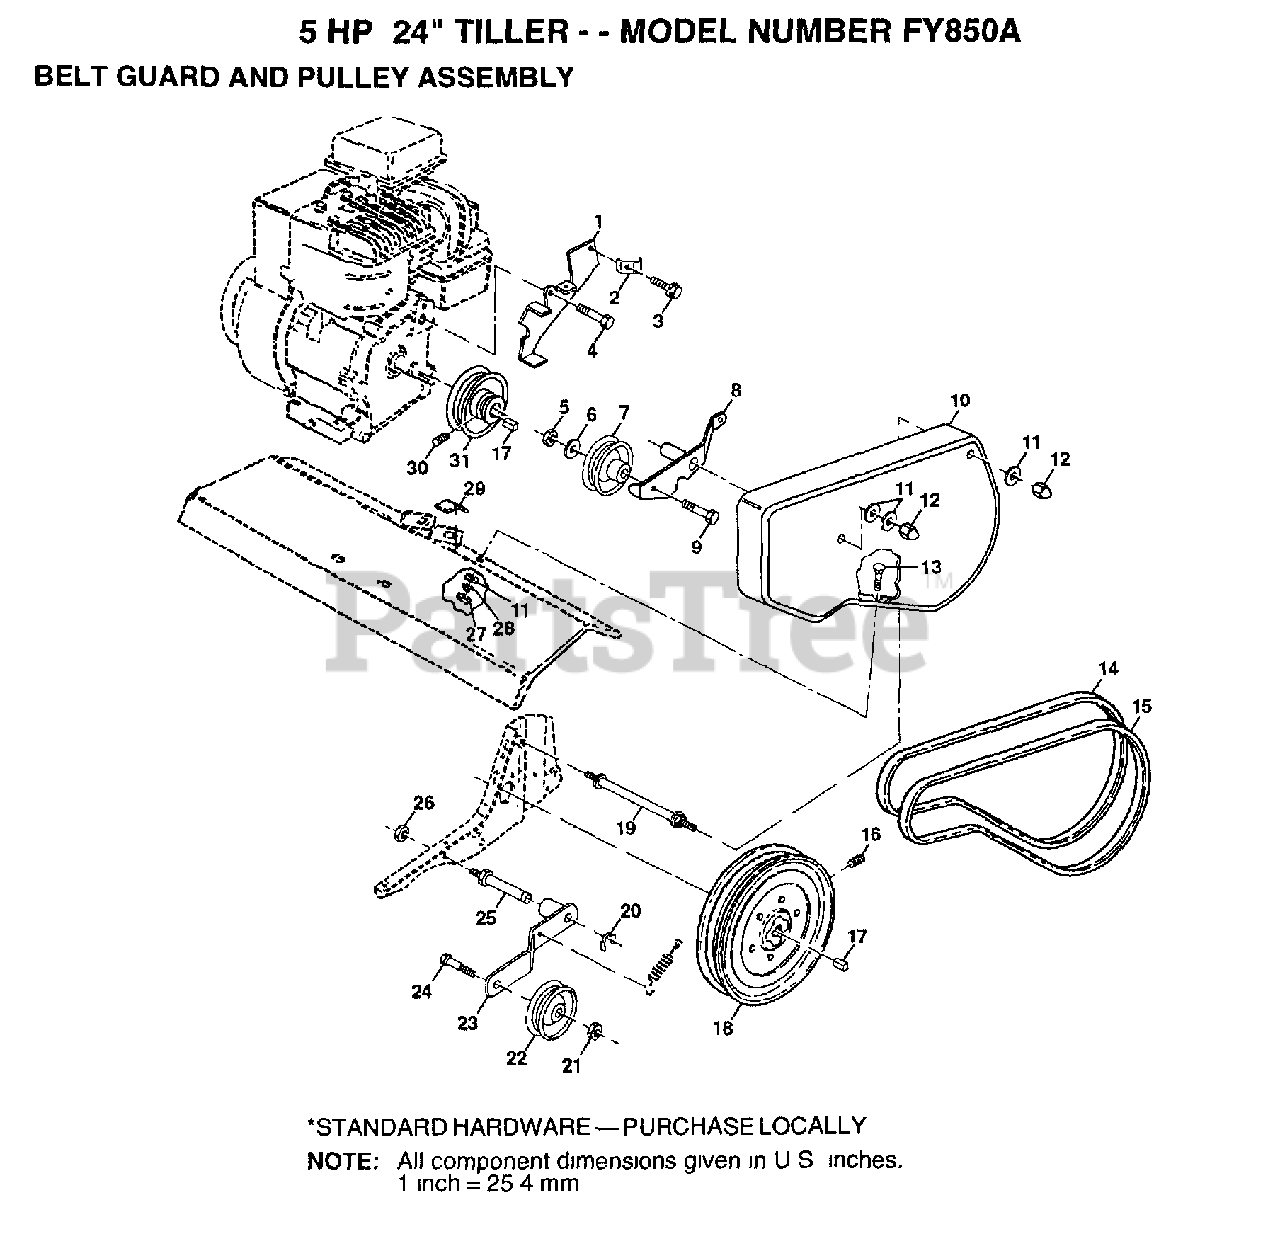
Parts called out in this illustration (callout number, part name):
2	CONDIUT CLIP T
5	NUT.HEX.3/8-16UNC
6	WASHER
7	PULLEY W/SPACER
8	ARM.ASM.REV.IDLER
11	WASHER
12	NUT-CAP TI
13	BOLT T
14	BELT-V
16	SET SCREW
17	KEY T
19	BOLT TI
20	KLIP RING TI
21	NUT
23	IDLER ARM TI
25	SHAFT IDLER TI
26	JAM NUT TI
28	LOCKWASHER
29	PAD IDLER TI
30	SET SCREW
31	ENGINE PULLEY TI
